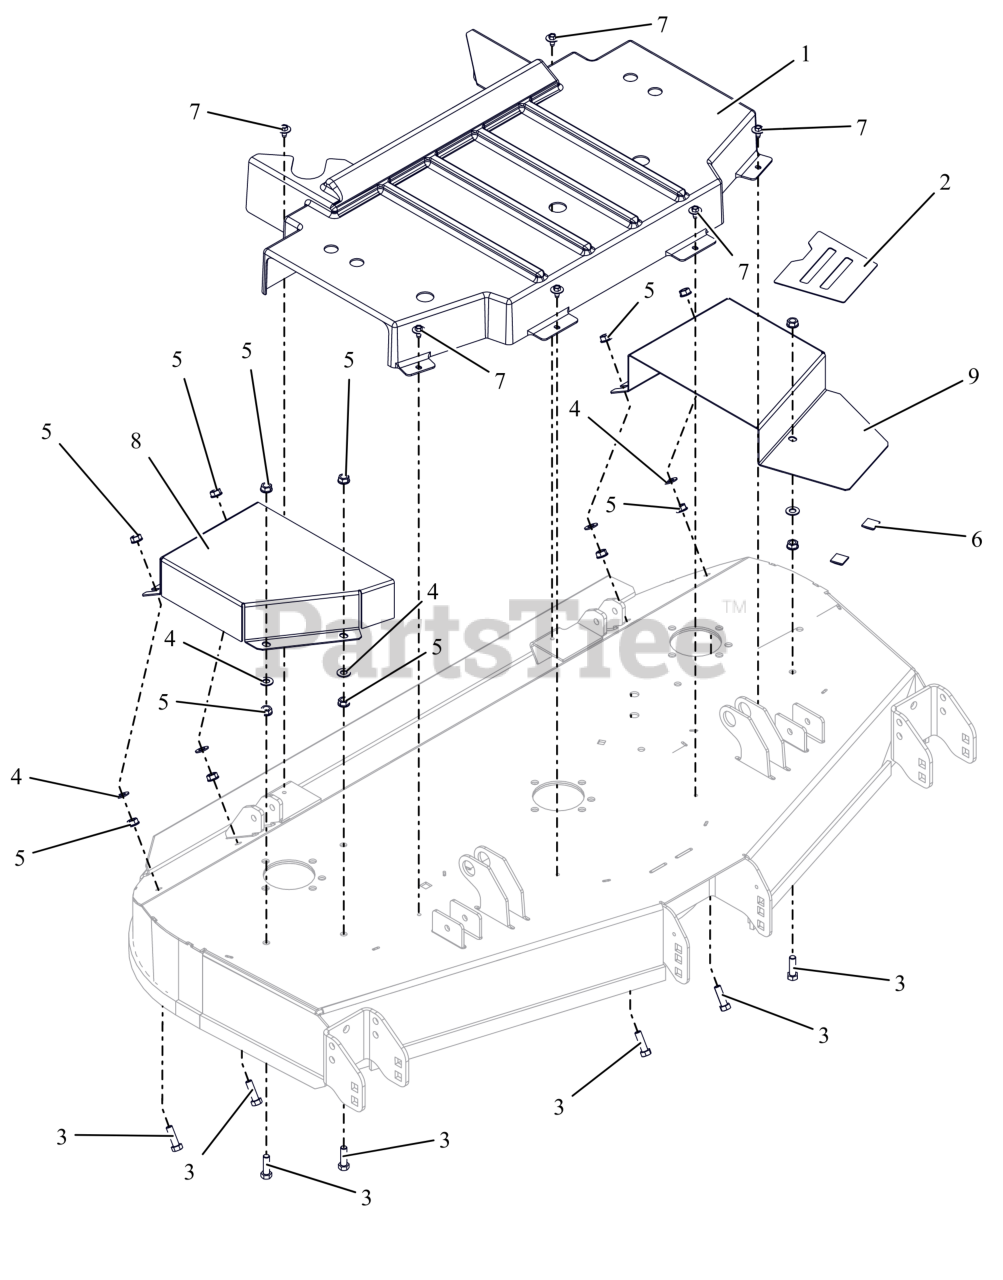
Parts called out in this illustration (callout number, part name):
1	GUARD,CENTER,DECK SPINDLE CE
2	GRIP TAPE 52-60 BELT COVER
3	BLT, HEX .38-16X1.25 G5 ZCC
4	WSHR,FLT .406X.812X.065 ZCC
5	NUT, SPNLK-FLG .38-16 G5 ZCC
7	SCR, TAP .25-20X.50 LG HWH ZCC
8	GUARD, BELT RH CE RD
9	GUARD, BELT 52 LH CE RD
